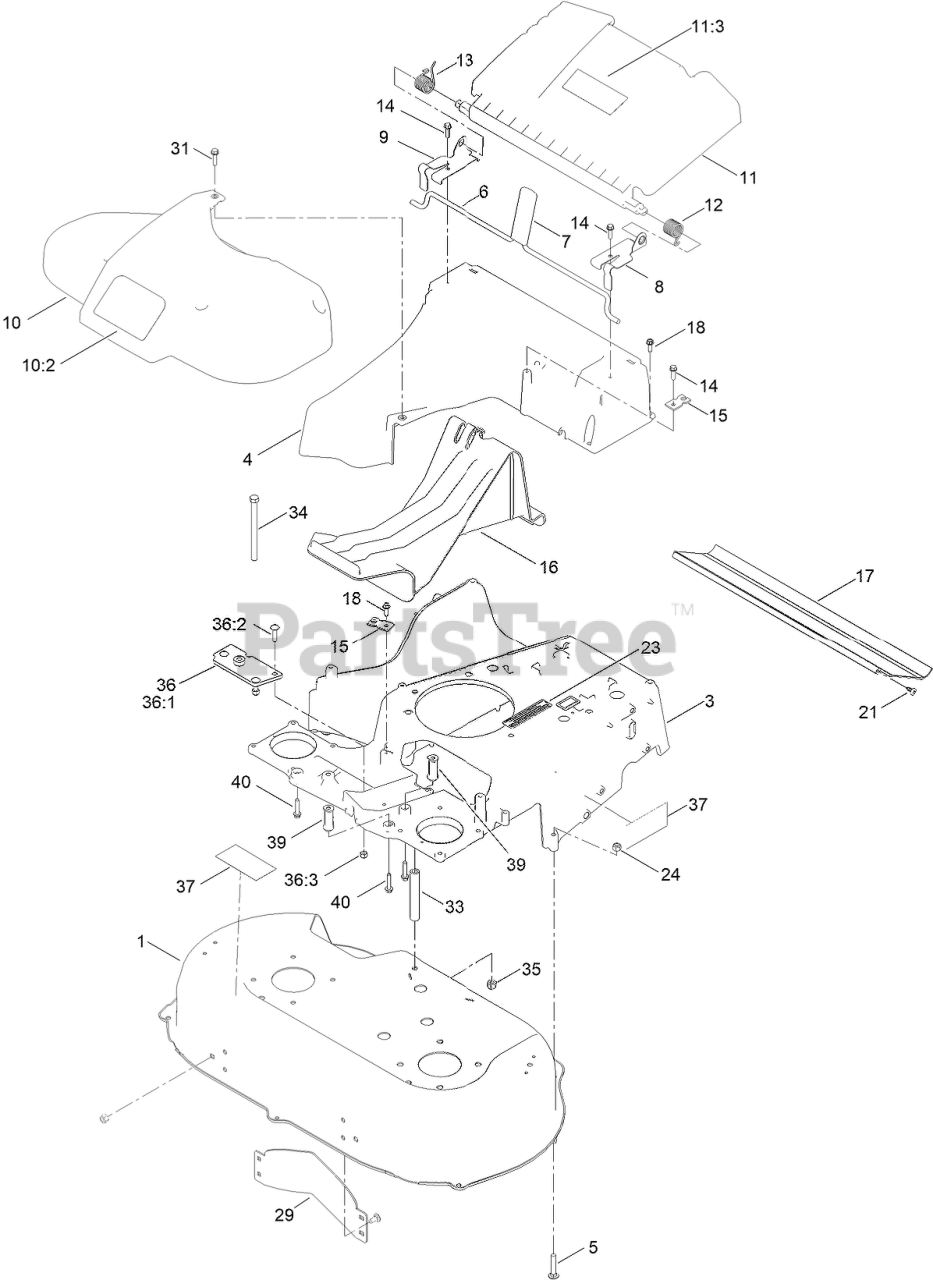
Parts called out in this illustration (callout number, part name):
1	HOUSING ASM
3	FRAME-30"
5	BOLT-CAR
6	ROD-RELEASE, HANDLE
7	GRIP-LEVER
8	BRACKET-DOOR, LH
9	BRACKET-DOOR, RH
10	BELT COVER ASM
10:2	DECAL-COVER, BELT
11	REAR DEFLECTOR ASM
11:3	DECAL-WARNING
12	SPRING-TORSION
13	SPRING-TORSION
14	SCREW-HWH
15	BRACKET-CABLE, TRACTION
16	PLUG-MULCH
17	SHIELD-TRAILING
18	SCREW-HWHTF
21	SCREW-PTH
23	DECAL-ARRESTOR, SPARK
24	NUT-LOCK, NI
29	BAFFLE-CONTROL
31	SCREW-HWHTF
33	SPACER-SHIELD
34	SCREW-HH
35	NUT-HEX
36	FRAME PLATE KIT
36:1	PLATE-FRAME
36:2	SCREW-CARR
36:3	NUT-LOCK, NI
37	DECAL-TOOL, THD
39	SPACER-FRAME, 30 IN.
40	SCREW-HWHTF
